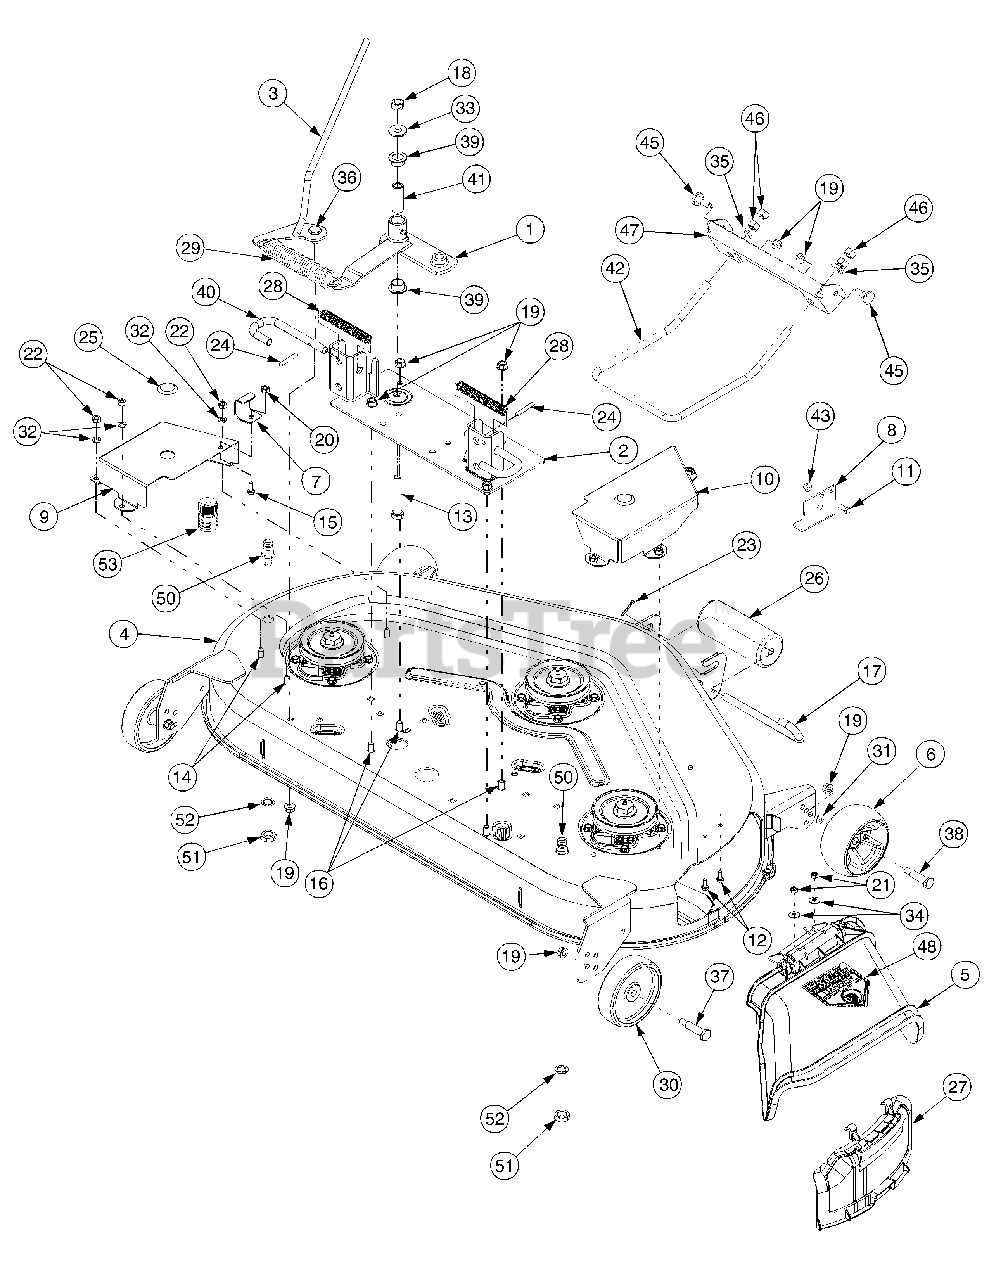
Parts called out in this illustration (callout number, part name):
1	Idler Assembly
5	Chute Assembly, Discharge
6	Wheel, Deck Ball
11	Screw, Hex Cap, 3/8-16 x1.0 Gr5
12	Screw, Hex Cap, 1/4-20 x .62
13	Screw, Hex Cap, 1/2-20 x 3.0
14	Screw, Self Tap, 5/16-18 x .75
15	Screw, Hex Cap, 5/16-18 x .75
16	Bolt, Carriage, 3/8-16 x .75 GR5
17	Pin, Roller, 1/2 Dia x 7.31
18	Nut, Hex Lock, 1/2-20
19	Nut, Flange Lock, 3/8-16
20	Nut, Flange Lock, 5/16-18
21	Nut, Hex, 1/4-20 GR5
22	Nut, Hex, 5/16-18, GR5
23	Pin, Cotter, 1/8 Dia x 1
24	Pin, Spiral Spring, 3/16 Dia x .75
25	Button Plug
26	Front Roller
27	Plug, Mulch
28	Spring, Comp, .66 OD x 1.8
29	Spring, Ext, .162 Dia x 1.25 OD
30	Wheel, Deck, 5.0 x 1.38
31	Washer, Belleville, .401 x .870x.63
32	Washer, Lock, 5/16
33	Washer, Flat, 1/2 x 1.25 x .10
34	Washer, Bell, .265 x .75 x .062
35	Washer, Flat, .531x1.062 x.134 HT
36	Bolt, Shoulder, .498 Dia x .340
37	Screw, Shoulder, .496 x 1.525:3/8-16
38	Bolt, Shoulder, .496 x 2.5:3/8-16
39	Bearing, Flange, 3/4 ID x .52 LG
40	Pin, Mower Support
41	Spacer, .5 OD x .75 x 2.07 Lg
42	Rod, Front Lift
43	Nut, Flange Lock, 3/8-16 GrF
45	Bolt, Shoulder, .50 Dia. x .494 Lg
46	Nut, Hex, 1/2-13 Gr5
48	Graphic, Danger
50	Nozzle, Deck Wash
51	Nut, Hex M16-1.5
52	Washer, Lock
53	Adapter, Water Nozzle
